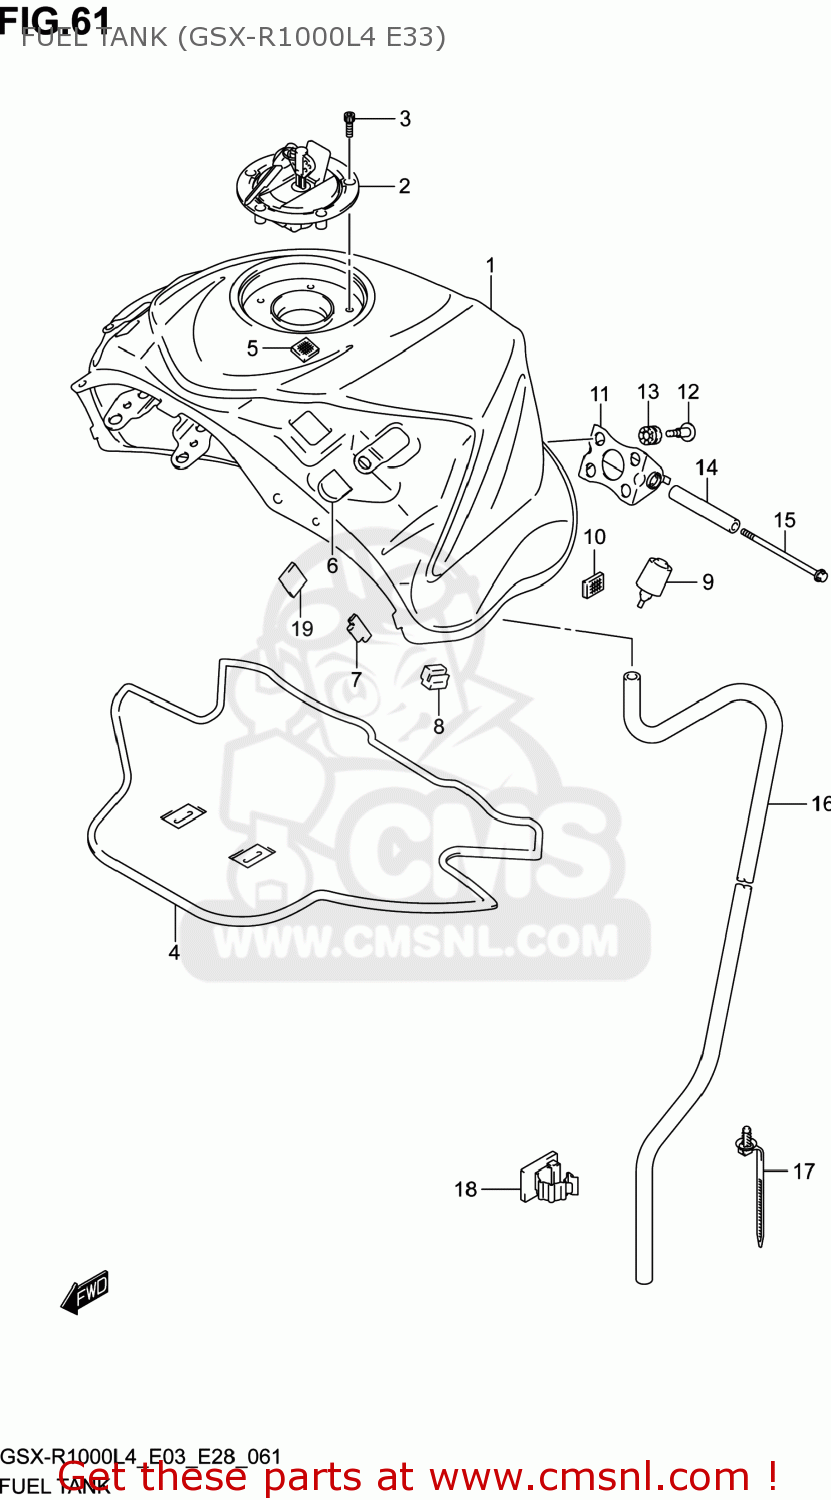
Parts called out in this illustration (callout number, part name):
1	TANK ASSY,FUEL(BLUE)
2	CAP SET,FUEL TANK
3	BOLT(5X20)
4	SHIELD,FUEL TANK HEAT
5	FASTENER
6	CUSHION
7	CUSHION,FUEL TANK COVER
8	CUSHION,FUEL TANK SIDE
9	CUSHION,FUEL TANK RR
10	FASTENER
11	BRACKET,FUEL TANK NO.1
12	SCREW(6X22)
13	CUSHION
14	SPACER,FUEL TANK RR
15	BOLT(6X110)
16	HOSE,FUEL TANK WATER DRAIN
17	CLAMP(L:154)
18	CLAMP
19	PAD
